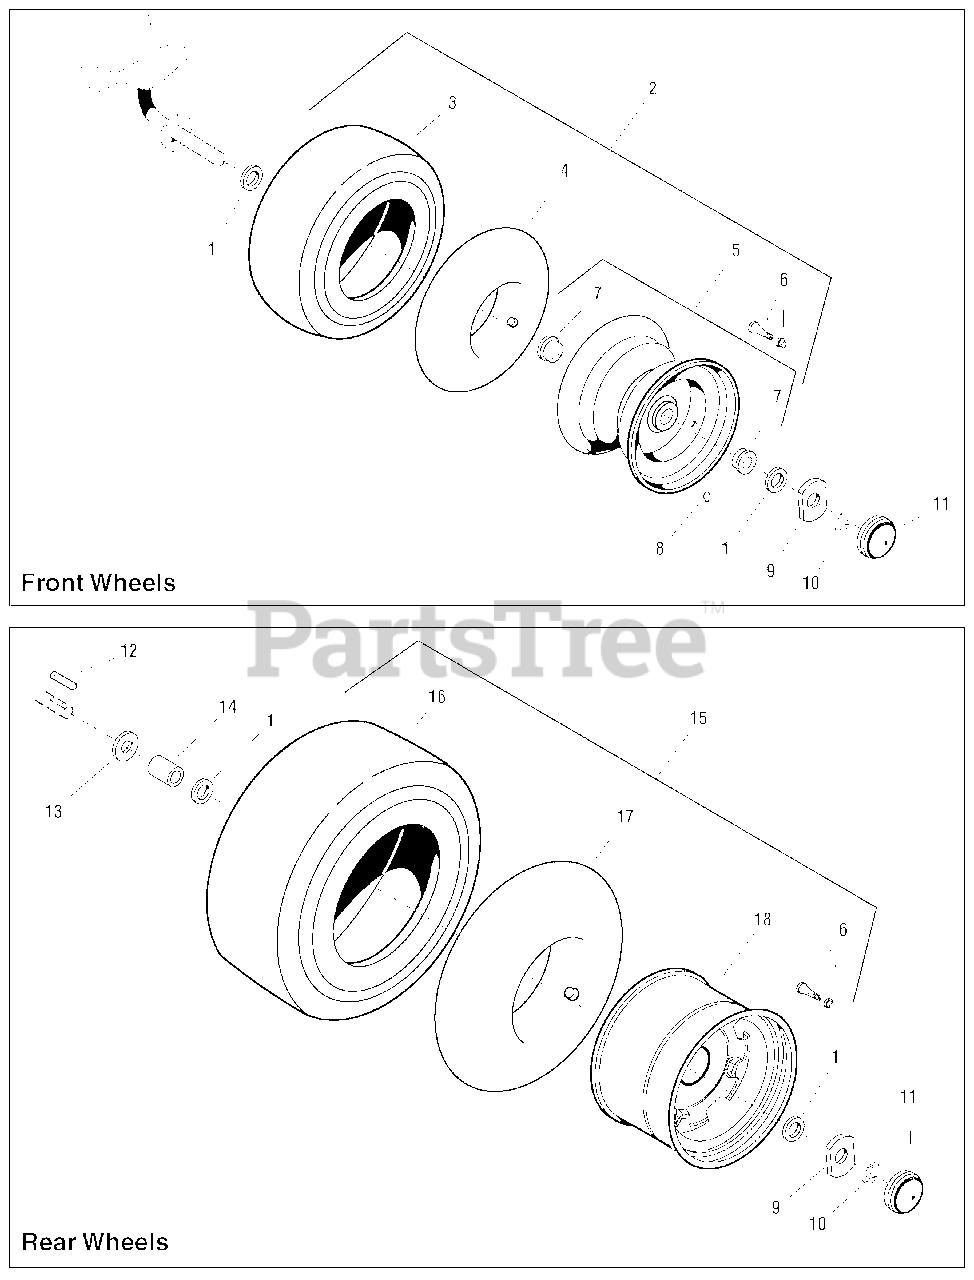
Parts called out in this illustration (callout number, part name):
1	WASHER, .828 ID x 1-5/8 OD
2	WHEEL & TIRE ASSEMBLY, Front
3	TIRE, Turf 15 X 6.00 - 6 Saver TL
4	TUBE, Tire, Front
5	WHEEL & BUSHINGS ASSEMBLY, Front
6	VALVE STEM & CAP
7	BEARING
8	FITTING, Grease, 1/4-28 Thread
9	WASHER, Special Yellow
10	RING, Retaining
11	CAP, Hub
12	KEY, 3/16 x 3/16 x 3
13	WASHER
14	SPACER, 0.77 ID x 1-1/4 OD x 1.65 LG
15	WHEEL & TIRE ASSEMBLY, Rear 20"
15	WHEEL & TIRE ASSEMBLY, Rear 22"
16	TIRE, Turf 22 X 8.00 - 8 Saver TL
16	TIRE, Turf 22 X 10.00 - 8 Saver TL
17	TUBE, Tire, Rear, 22 x 8 - 8
17	TUBE, Tire, Rear, 20 x 10 - 8
18	WHEEL, Hub
